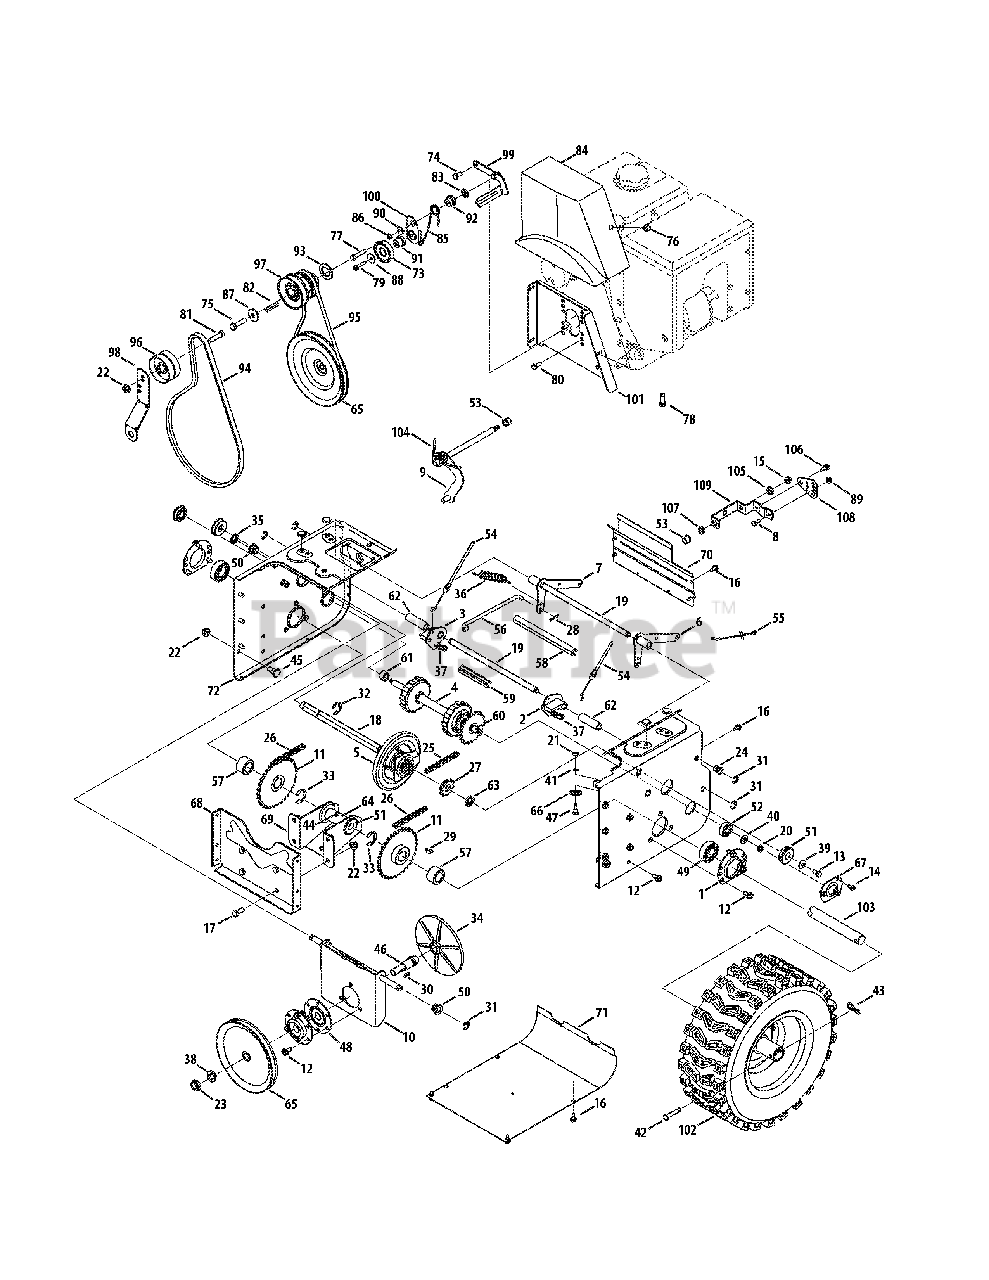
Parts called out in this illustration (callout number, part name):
1	Housing, Bearing
2	Dogg, Steering Drive, LH
3	Dogg, Steering Drive, RH
4	Shaft Assembly, Steering
5	Assembly, Friction Wheel
5	Wheel, Friction, Bonded
5	Screw, Hex Wash
6	Bracket, Auger Actuator
7	Bracket, Drive Actuator
8	Hex Head Screw, 1/4-20
9	Rod Assembly, Shift
10	Brkt, Friction Drive Suprt.
11	Sprocket, 32T
12	TT Screw, 5/16-18 x .750
13	Screw, Hex Cap Lock,
14	Screw, Hex, 1/4-20 x .50
15	Flange Lock Nut 5/16-18
16	Screw, Hex Wash.
17	Screw, Hex Cap, 3/8-16
18	Shaft, Hex Drive
19	Shaft, Actuator
20	Nut, Hex Insert Jam Lock
21	Nut, Hex, 1/4-28 GR5
22	Nut, Hx Flnge Insert Lk
23	Nut, Hx Insert Jam Lk
24	Rivet Nut, 3/8-16
25	Chain, Endless, #41 x 36L
26	Chain, #420 x 40L
27	Sprocket, #41 x 10T
28	Pin, Internal Cotter
29	Key, Woodruff
30	Key, Hi-Pro, 3/16 x 5/8
32	Ring, Retaining
33	Ring, Retainer
34	Plate, Drive
35	Speed Nut, .500
36	Spring, Extension
37	Spring, Extension
38	Washer, Lock, 5/8
39	Wsh, Bell., .34 x .872 x .06
40	Wash, .375 x .812 x .060
41	Washer, Lock, 1/4
42	Pin, Clevis
43	Pin, Internal Cotter
44	Fitting, Lube, 3/16 Drive
45	Screw, Shldr., .498 x .34
46	Spindle, Drive Plate
47	Screw, Hex Shldr., 1/4-28
48	Ass’y, Bearing/Housing
49	Bearing, Self Aligning
50	Bearing, Hex Flange
51	Bearing, Ball
52	Bush, Flg, .5625 ID x 1.375 x .4375
53	Bush, Flg, .5 ID x .627 OD
54	Cable, Steering
55	Cable, Auger Idler
56	Rod, Drive Clutch
57	Spacer, 1.01 x 1.50 x .93
58	Spacer, .49 x 7.865
59	Spacer, .49 x 3.545
60	Spacer, .566 x .87 x .190
61	Spacer, .566 x .87 x 1.25
62	Spcr., .514 x .632 x 2.44
63	Spacer, .675 x 1.0 x .23
64	Spcr, .6725 x 1.125 x 2.48
65	Pulley, Drive
66	Roller, Cable
67	Retainer Bracket
68	Bracket, Frame Support
69	Bracket, Axle Support
70	Cover, Upper Frame
71	Cover, Lower Frame
73	Idler Pulley Assembly
74	Screw, Hex 5/16-24 x .75
75	Screw, Hex 3/8-24 x 1.25
76	Screw, Hx Wash Hd Tapp
77	Screw, Hex Cap, 5/16-24 x 1.50
78	Screw, 3/8-16 x 1.00
79	Screw, 1/4-20 x 1.25
80	Screw, Shldr., .500 x .145
81	Screw, Hex Cap, 3/8-16 x 1.75
82	Key, Square, 1/4 x 1.5
83	Nut, Push
84	Cover, Belt
85	Torsion Spring, .850 dia. x .333 lg.
86	Washer, Lock, 5/16
87	Washer, Flat, .45 x 1.5
88	Washer, Flat, .265 x 1.0 x .030
89	Flange Lock Nut 1/4-20
90	Shldr. Spacer, .3175 x .500 x .094
91	Shldr. Spacer, .260 x .785 x .538
92	Shoulder Spacer, .340 x 1.00
93	Spacer, 1.02 x 1.63 x .1425
94	V-Belt, 4L x 44.60
95	V Belt, 3/8 x 36.68
96	Pulley, Flat Idler, 2.75 OD
97	Double Pulley, 3.25 x 2.75
98	Bracket, Auger Idler
99	Belt Keeper Bracket
100	Idler Drive Wheel Bracket
101	Belt Cover Bracket
102	Wheel Ass’y. - LH
102	Wheel Ass’y. - RH
103	Axle, Wheel, 45"
104	Torsion Spring, .750 I.D. x .968 Lg.
105	Flat Washer, .469 x .875 x .105
106	Shoulder Screw, .368 x .113
107	Spacer, .515 ID x .750 OD x .220
108	Speed Selector Pivot Bracket
109	Speed Selector Shift Bracket
